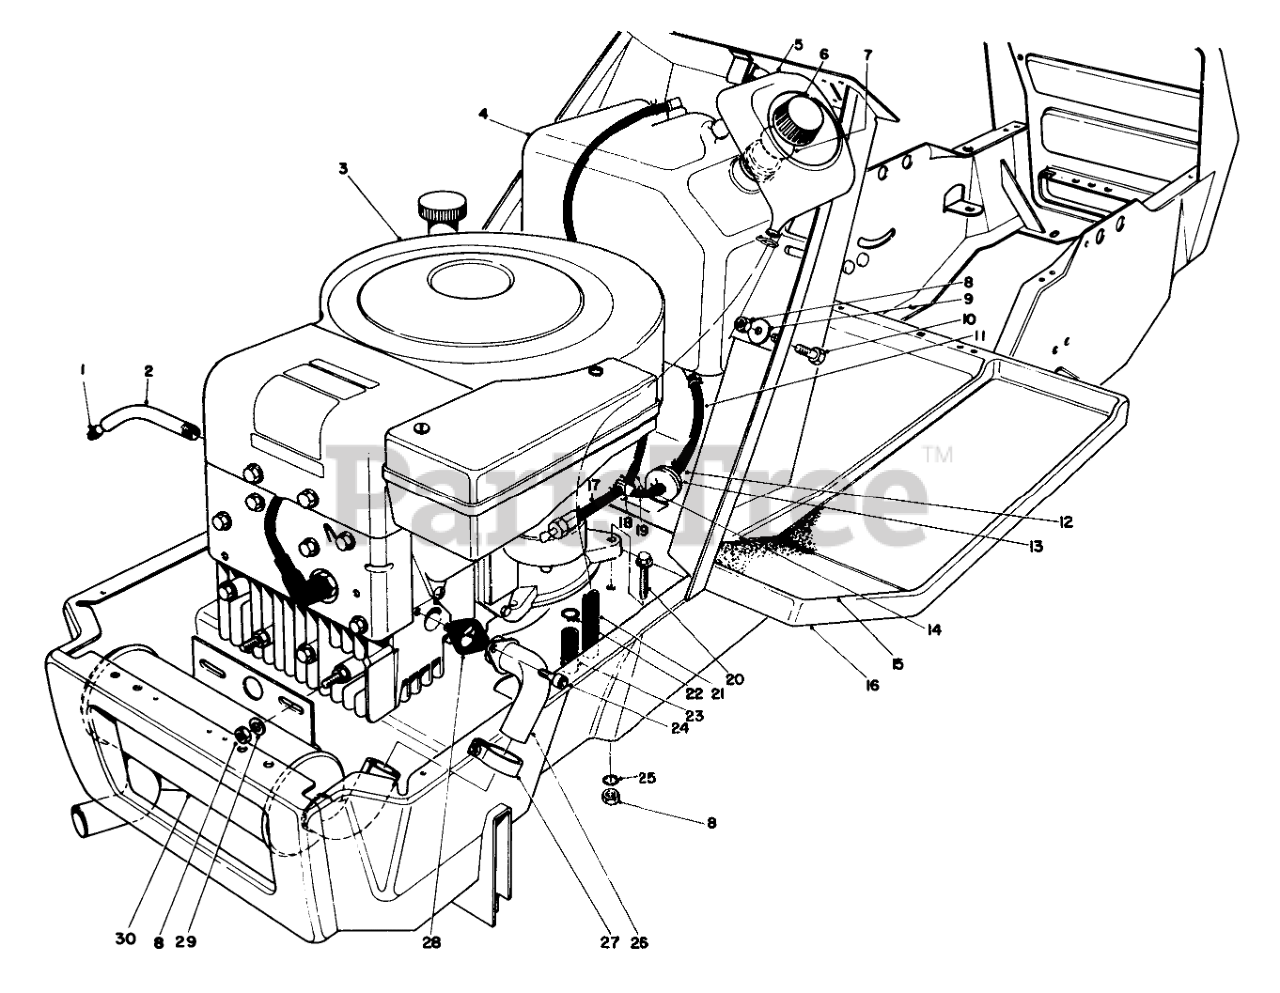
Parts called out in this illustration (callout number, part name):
1	PLUG-PIPE, SQH
2	OIL DRAIN TUBE
3	Engine
4	Gas Tank Assy. (Incl. Ref. #5)
5	Funnel-Overflow
6	Gas Cap Assy. (Incl. Ref. #7)
7	Gasket Gas Cap
8	NUT-LOCK, CONE
9	WASHER
10	SCREW-HH
11	GAS HOSE
12	Clamp
13	Nut
14	Hose Gas Return
15	LH FOOT TREAD
16	Frame
17	Hose Gas
18	Fitting-Barbed Y
19	Hose Gas
20	SCREW-HH
21	FUNNEL HOSE
22	HOSE CLAMP
23	CARB DRAIN HOSE
24	SCREW-HSH
25	WASHER-LOCK, INTERNAL
26	Exhaust Pipe
27	MUFFLER CLAMP
28	Exhaust Gasket
29	WASHER-PLAIN
30	EXHAUST MUFFLER 10 HP
